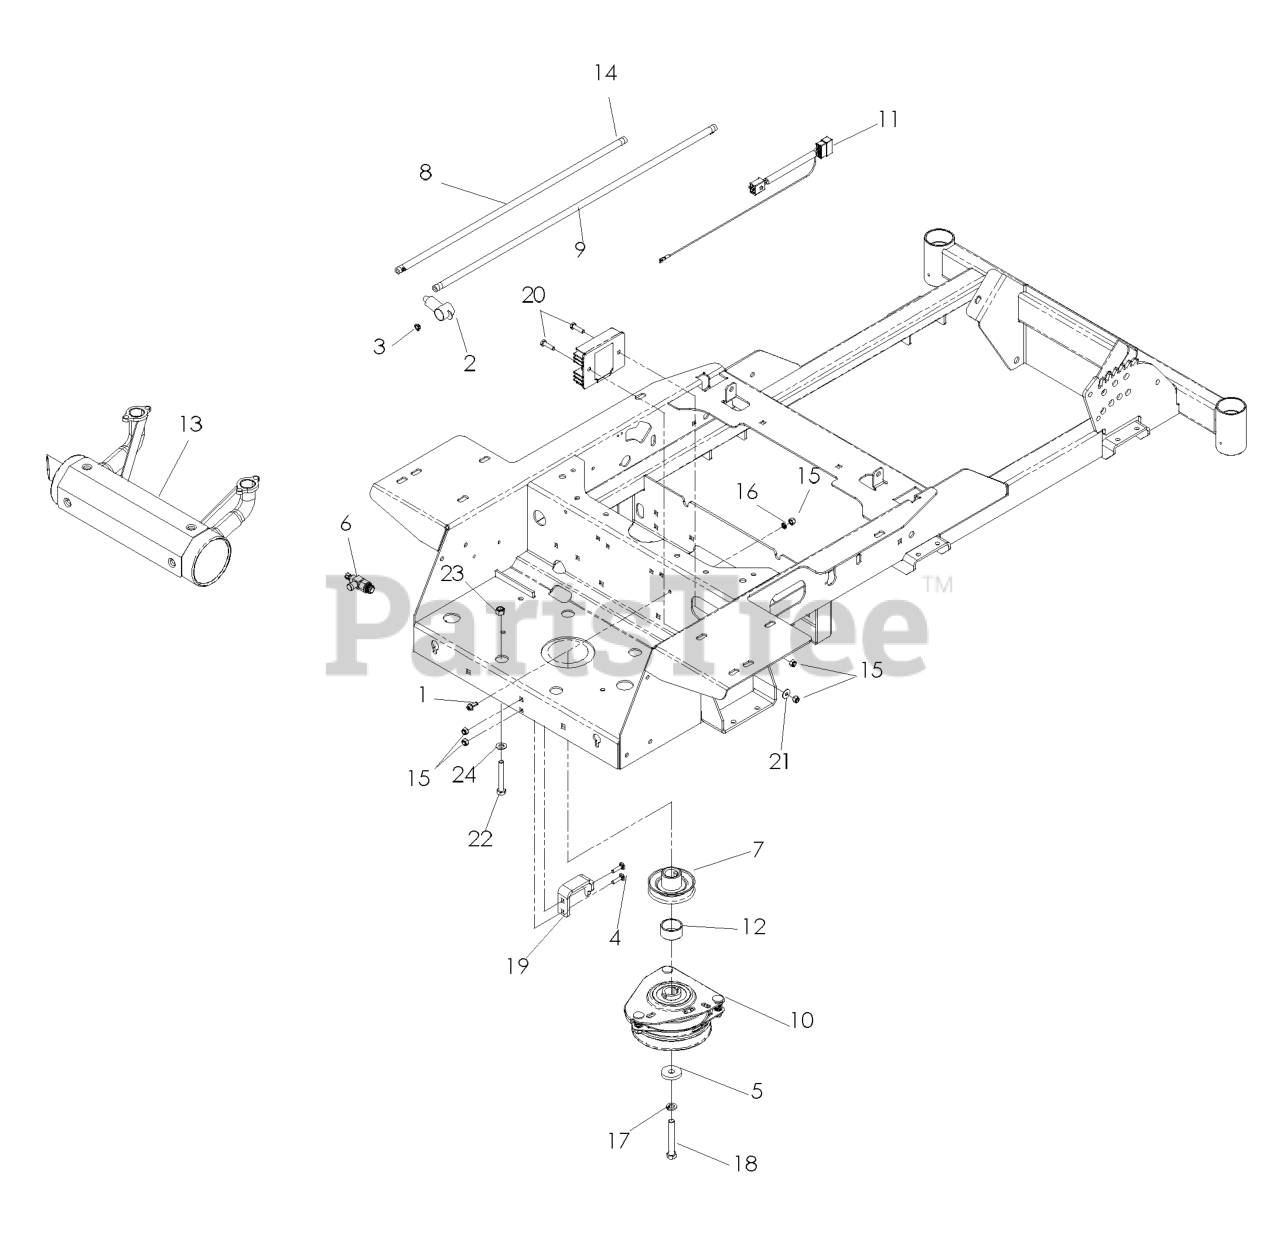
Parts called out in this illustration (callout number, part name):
1	SCREW- 1/4-20 X 5/8
2	INSULATOR
3	JAM NUT 1/4C
4	RHSNB, 1/4-20 X 1, GR5
5	CLUTCH, WASHER
6	OIL DRAIN ADAP.(HONDA)
7	PULLEY, ENGINE
8	FUEL LINE 24"
9	FUEL LINE 29.5"
10	CLUTCH.ELECTRIC.LT.48"*
11	PIGTAIL, HONDA
12	SPACER, ENGINE - PULLEY
13	MUFFLER HONDA
14	HOSE CLAMP
15	NUT 1/4-20 NYLOC
16	WASHER 1/4 INT TOOTH
17	WASHER 7/16 LOCK
18	HEX SCREW 7/16-20 X 3
19	TIE DOWN, CLUTCH
20	HCS 1/4 X 1
21	WASHER 1/4 FLAT
22	HCS 5/16C X 1 3/4
23	NUT 5/16 NYLOC
24	WASHER 5/16 FLAT
